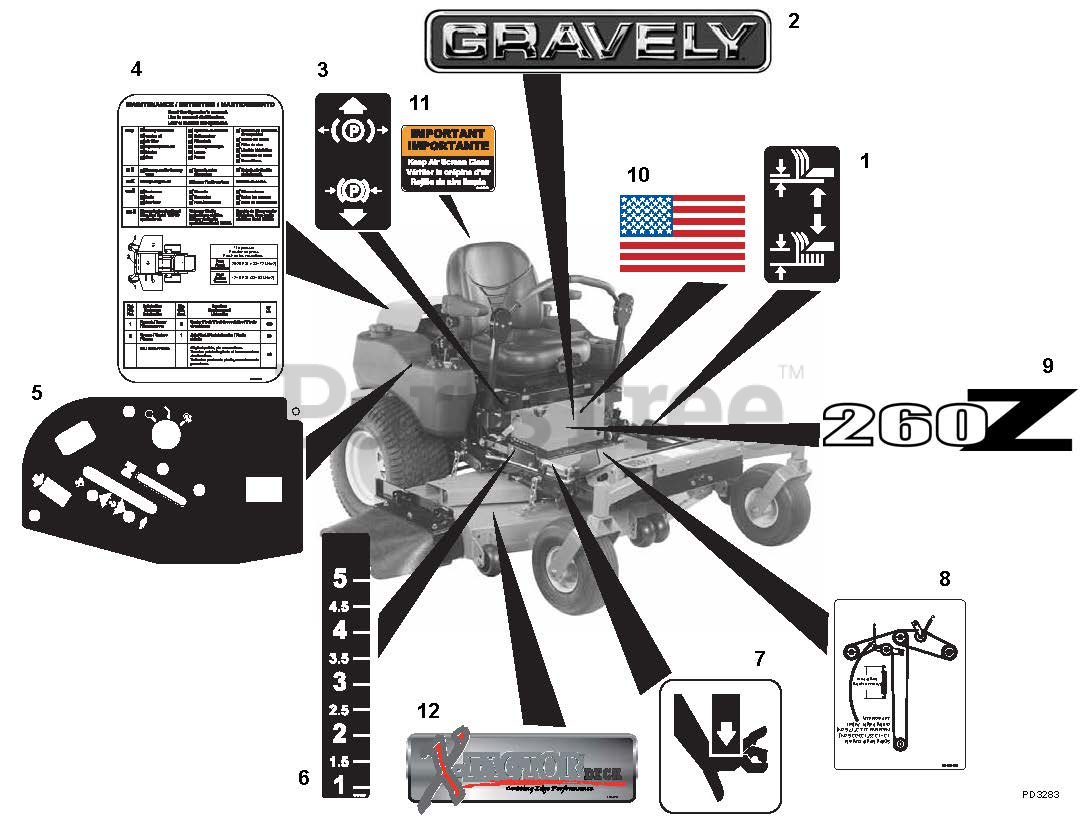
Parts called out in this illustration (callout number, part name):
1	Decal, Lift Lever
2	Decal, 15 in. Gravely Logo
3	Decal, Parking Brake Lever
4	Decal, Maintenance Instructions
5	Decal, Control Panel
6	Decal, Height of Cut
7	Decal, Pinch Point
8	Decal, Belt Diagram
9	Decal, PM-260Z
9	Decal, PM-272Z
9	Decal, PM-252Z
9	Decal, PM-266Z
10	Decal, American Flag
11	Decal, Warning Clean Debris
12	Decal, X-Factor Deck
